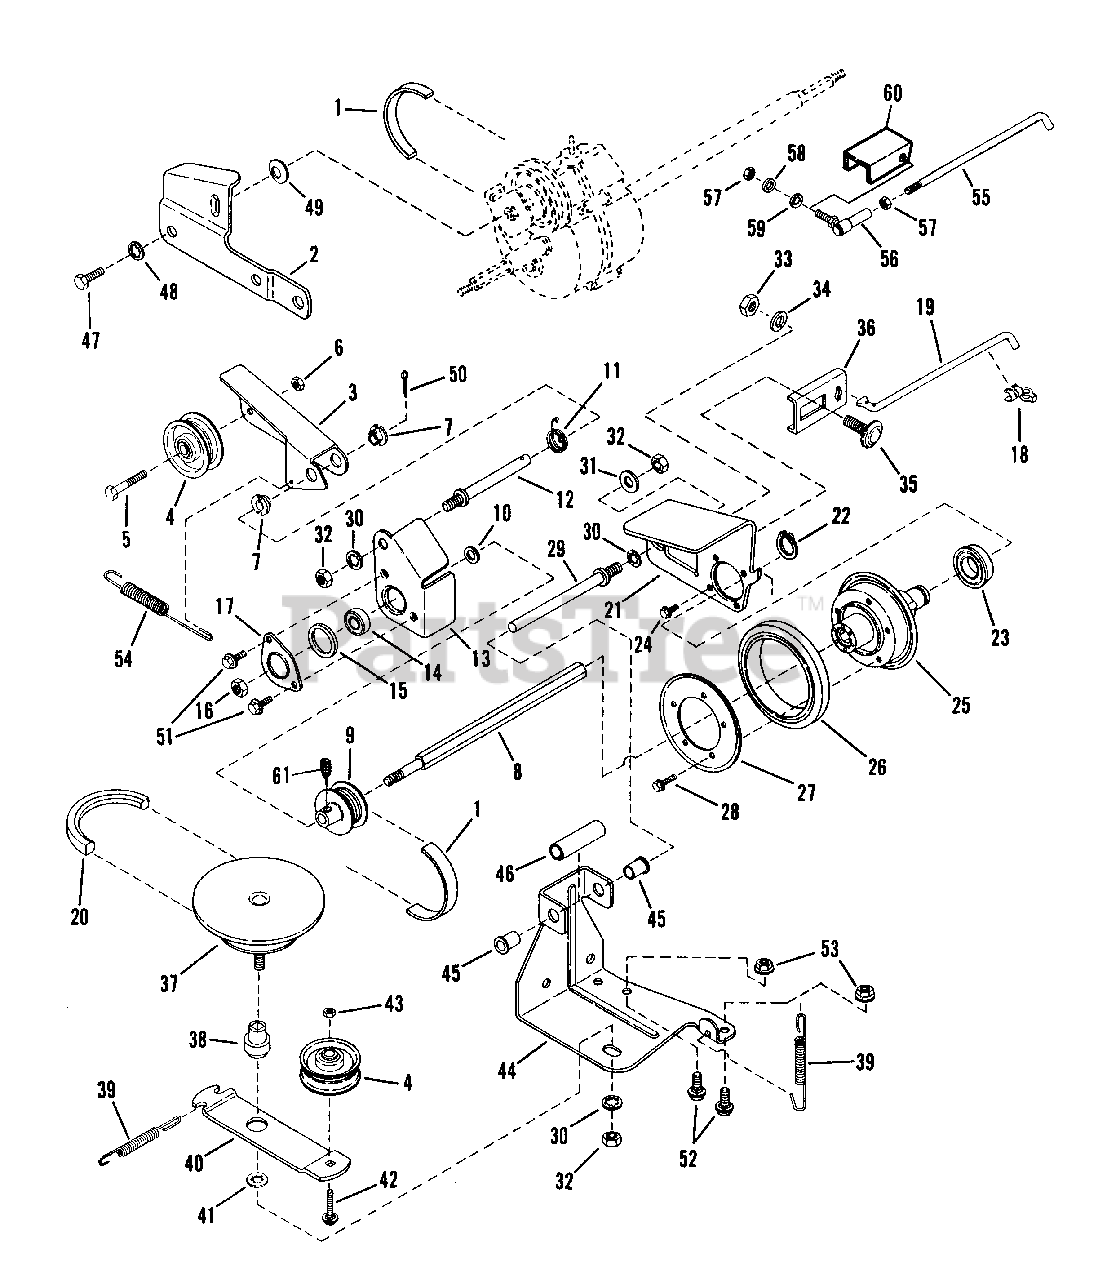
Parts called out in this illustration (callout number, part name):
1	BELT, Poly-Vee
2	LINK, Differential
3	ARM, Clutch Idler
4	PULLEY, Idler
5	SCREW, 1/4-28 x 1-3/8" Hex Head Cap
6	NUT, 1/4-28 Hex Top Lock
7	BUSHING, 3/8 I.D. Nylon
8	HEX-SHAFT
9	PULLEY, 2" O.D.
9	*PULLEY, 1-3/4" O.D.
10	WASHER, .390 I.D. Flat
11	SPRING, Torsion
12	STUD
13	HOLDER, Bearing (Inner Half)
14	BEARING, Ball
15	O-RING
16	NUT, 3/8-24 Hex Center Lock
17	HOLDER, Bearing (Outer Half)
18	CLIP, 1/4 Right Arc (Transfer Rod)
19	ROD, Transfer
20	BELT, Engine Drive
20	*BELT, Engine Drive
21	PLATE, Thrust
22	RING, 3/4" External Retaining
23	BEARING, Ball
24	SCREW, #10-32 x 1/4" Self-Tapping Machine
25	ASSEMBLY, Hub
26	RING, Driven
27	PLATE, Ring Retaining
28	SCREW, #10-24 x 1/2" Hex Washer Self-Tap (Torx)
29	GUIDE, Thrust Plate
30	WASHER, 3/8" Internal Tooth Lock
31	WASHER, 3/8" Flat
32	NUT, 3/8-24 Hex, Grade 2
33	NUT, 5/16-18 Hex
34	WASHER, 5/16" Split Lock
35	BOLT, 5/16-18 x 3/4" Carriage, Grade 5
36	CONNECTOR, Transfer Rod
37	ASSEMBLY, Drive Disc
38	BUSHING
39	SPRING (Wheel Drive & Idler)
40	ARM, Idler
41	RETAINER, 3/8" Bolt
42	BOLT, 1/4-20 x 1-1/2" Carriage, Grade 5
43	NUT, 1/4-20 Hex Center Lock
44	BRACKET, Deck
45	BUSHING, Flange
46	SPACER
47	SCREW, 5/16-18 x 1/2" Hex Head Cap, Grade 5
48	WASHER, 5/16" Internal Tooth Lock
49	WASHER, Spring
50	PIN, 3/32 x 1/2" Cotter
51	SCREW, 1/4-20 x 1/2" Hex Flange Self-Tap
52	BOLT, 5/16-18 x 5/8" Short Neck Carriage, Grade 5
53	NUT, 5/16-18 Hex Flange Lock
54	SPRING, Clutch
55	**LINK, Transfer
56	**JOINT, Ball
57	**NUT, 1/4-28 Hex
58	**WASHER, 1/4" Flat
59	**WASHER, 1/4" Internal Tooth Lock
60	SHIELD, Hex Shaft
61	*SCREW, 1/4-28 x 1/4" Countersunk Set
